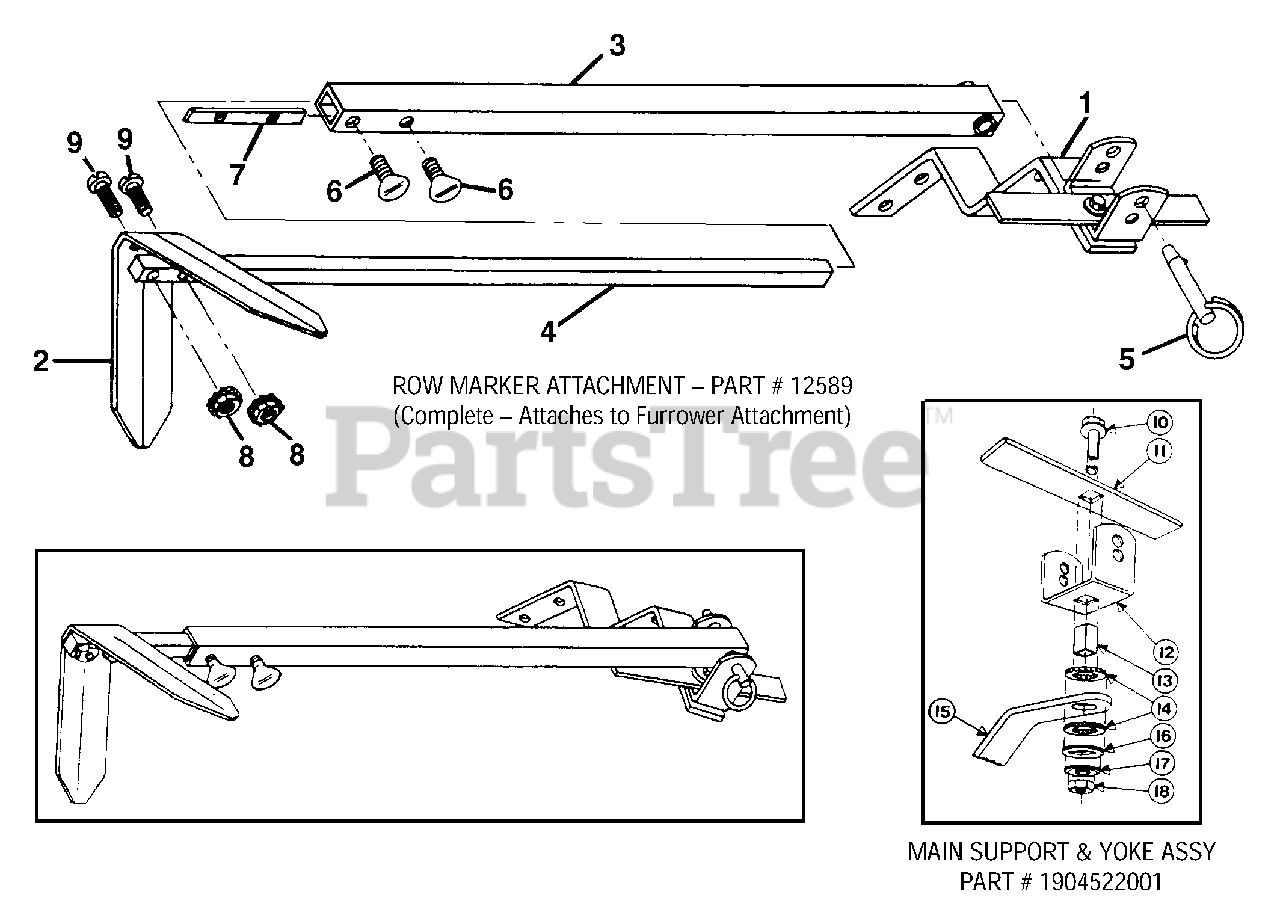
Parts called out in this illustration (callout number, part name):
1	Main support & yoke assembly Complete
2	Marker blade, (blade only)
3	Marker arm, main arm
4	Marker arm, ext. arm w/stop pin
5	Hitch pin
6	Thumbscrew, 1/"-20 x 1/2
7	Nut bar
8	Nut, hex, No. 10-24 w/star washer
9	Screw, round hd., 10-24 x 1
10	Screw-hex flanged locking, 3/8-16 x 1-1/2 Grade 5
11	Stop Bar
12	Yoke
13	Tube Key-square
14	Washer-friction
15	Main Support
16	Washer-square hole
17	Washer-disc spring
18	Nut-hex 3/8-16
12589	Row Marker Attachment
1904522001	Row Marker Main Support & Yoke Assembly
